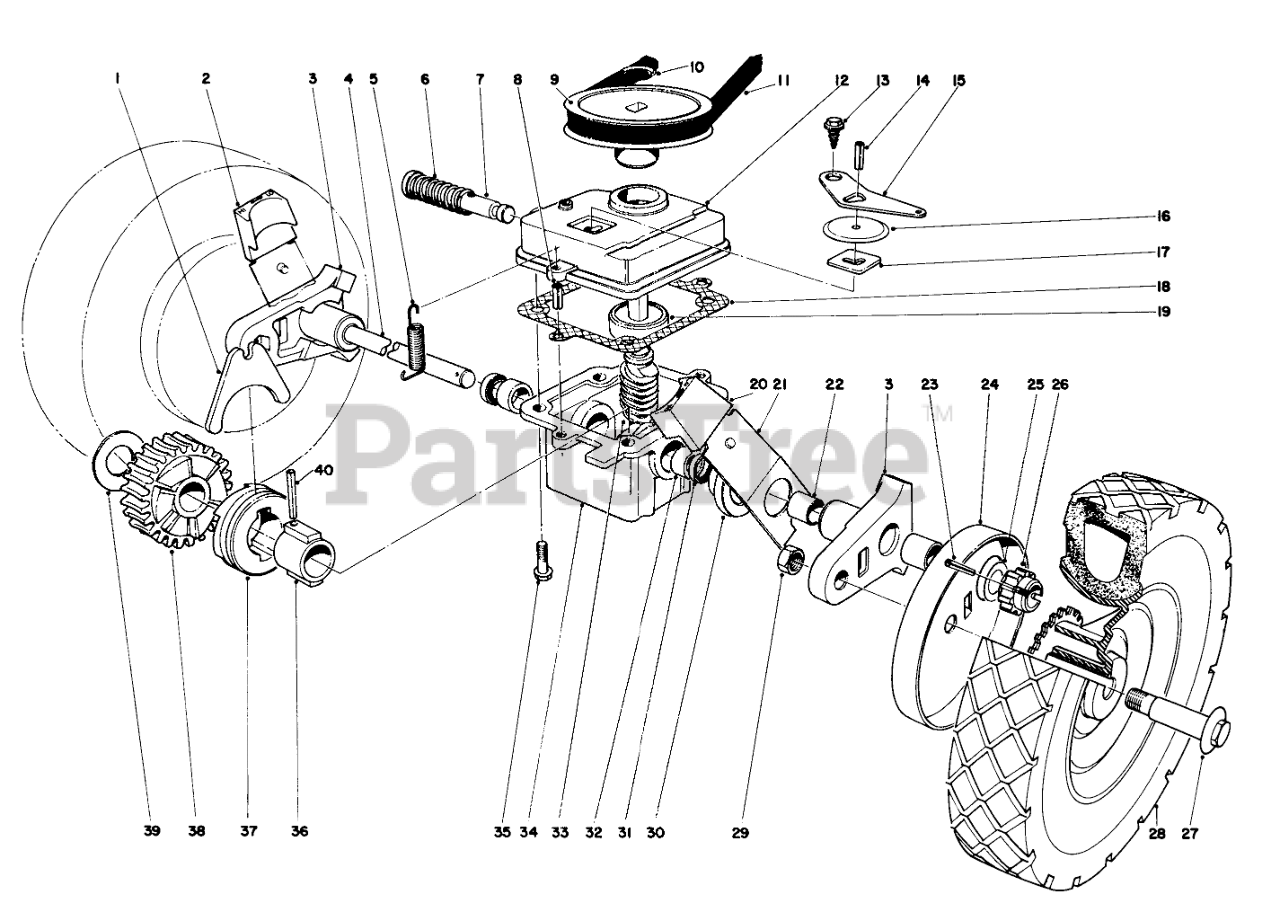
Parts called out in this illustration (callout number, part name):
1	SHIFTER FORK
2	Arm Knob
3	Pivot Arm (Incl. Ref. No. 22)
4	Drive Shaft
5	TENSION SPRING
6	SPRING
7	Shift Rod
8	3/16 X 1/2 ROLL PIN
9	PULLEY
10	PUSH-ON 93-3236
11	V BELT
12	GEAR CASE COVER
13	Screw
14	PIN-ROLL
15	SHIFTER ARM
16	TRANS DUST COVER
17	LATCH PLATE
18	GASKET
19	Bearing
20	Arm Knob
21	Spring Arm
22	BUSHING
23	PIN-GROOVED
24	WHEEL COVER
25	WASHER-THRUST
26	Pinion
28	Wheel & Tire
29	Nut
30	End Cap
31	Seal
32	Bushing
33	WORM SHAFT
34	Gear Case (Incl. Ref. 31-32)
35	Screw
36	SLEEVE
37	CLUTCH JAW
39	THRUST WASHER
40	COIL PIN
